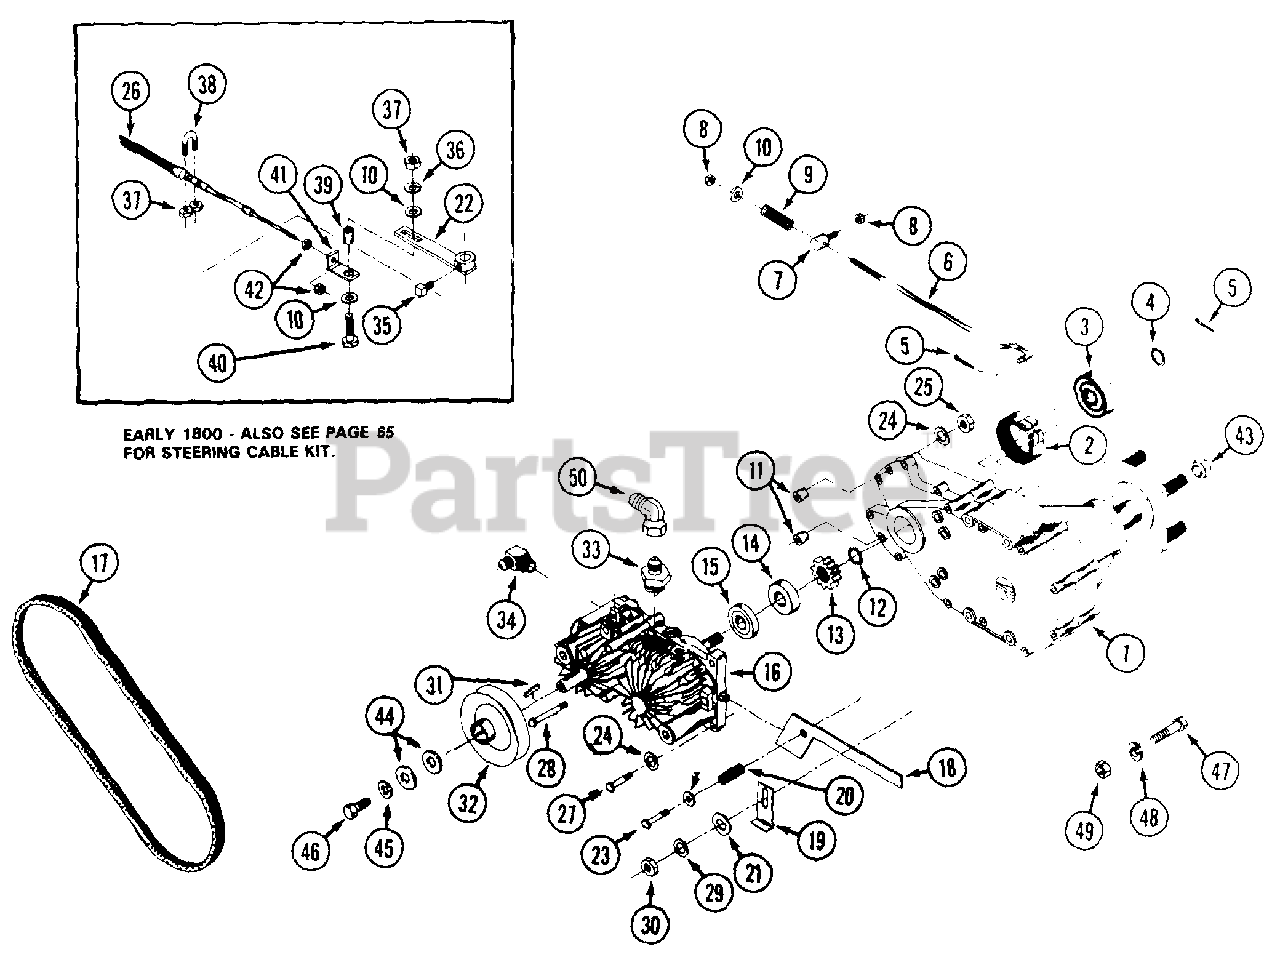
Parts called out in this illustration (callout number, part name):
1	TRANSMISSION - ZT
5	PIN - cotter 1/8" x 1"
8	NUT - lock 1/4"-20
10	WASHER - 1/4"
12	RING - snap
14	BEARING
16	PUMP - hydro L.H.
17	BELT - pump drive
18	LEVER - transmission dump
19	BRACKET - dump lever stop
20	SPRING - compression
21	WASHER - 3/8"
22	ARM - transmission
23	BOLT - dump lever
24	LOCKWASHER - 5/16"
25	NUT - 5/16"-18
27	BOLT - 5/16"-18 x 1-3/4"
28	BOLT - 5/16"-18 x 7-1/2"
29	LOCKWASHER - 3/8"
30	NUT - 3/8"-16
31	KEY - 5 x 5 x 25mm
32	PULLEY - 4" OD x 15mm ID
33	FITTING - male adapter
34	FITTING - male adaptor 90°
35	SCREW - set 5/16"-18 x 1/2" square head
36	LOCKWASHER - 1/4"
37	NUT - 1/4"-20
38	CLAMP - cable
39	BUSHING - cable
40	BOLT - 1/4"-20 x 1"
41	BRACKET - cable end
42	NUT - lock #10-32
43	NUT - lug 1/2"-20
44	WASHER - .625" x 1"
45	WASHER - .312" x .875"
46	BOLT - M6-1.0 x 12 mm flange
47	BOLT - 3/8"-16 x 3-1/2" mounting
47	BOLT - 3/8"-16 x 4" mounting
48	LOCKWASHER - 3/8"
49	NUT - 3/8"-16
50	FITTING - 90° male to female
